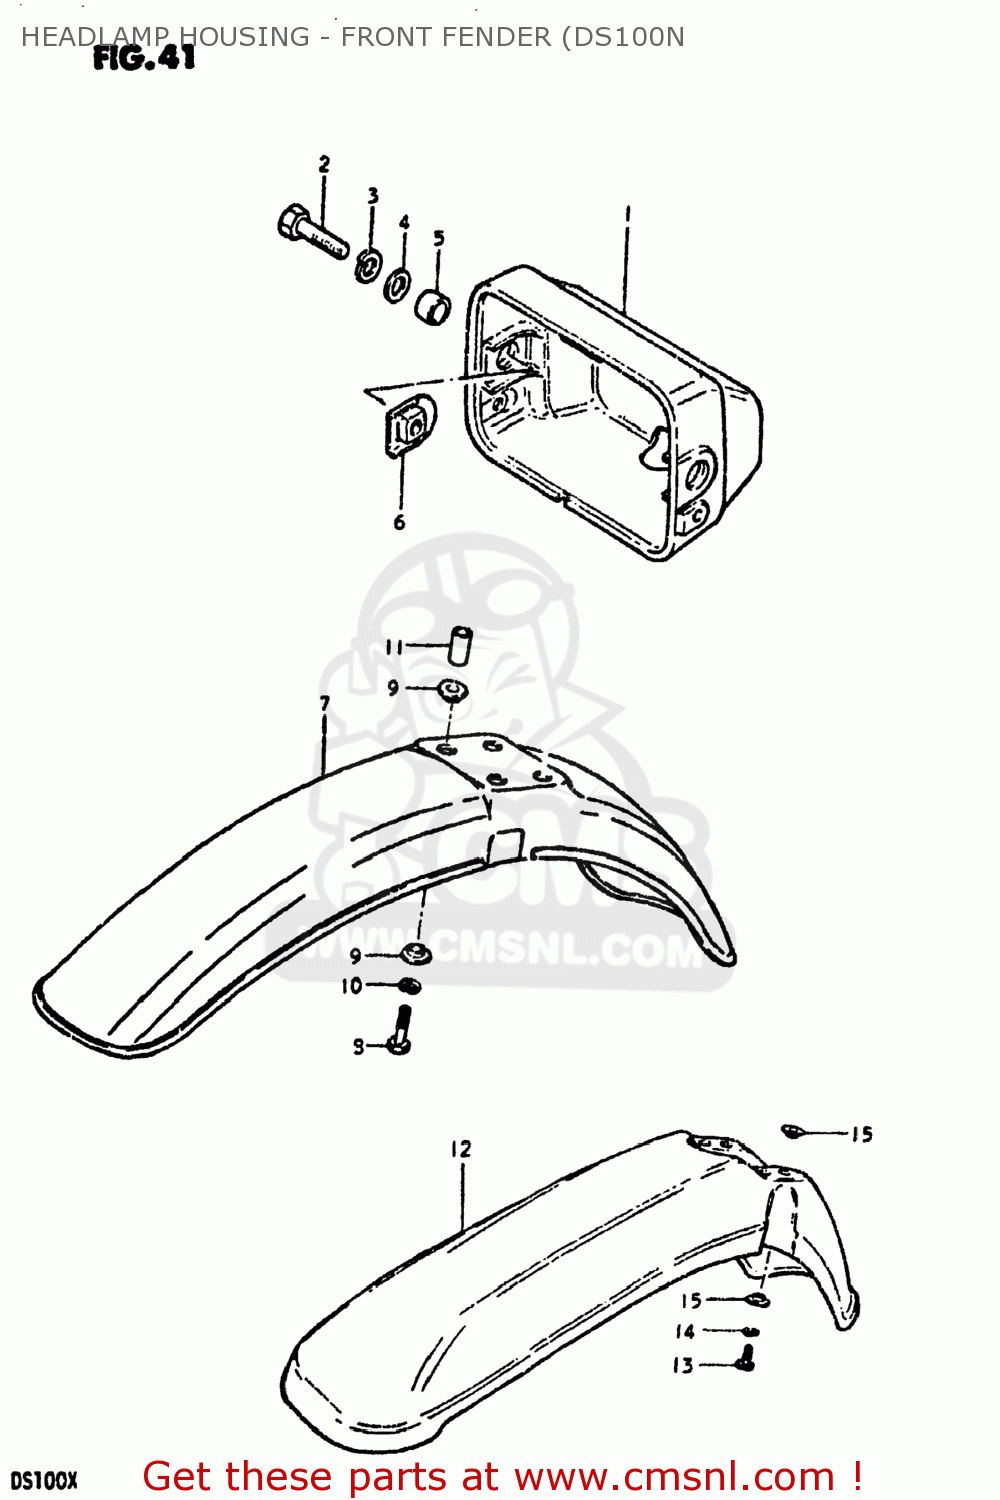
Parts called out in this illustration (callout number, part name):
1	HOUSING,HEADLAMP
2	BOLT
3	WASHER
4	LOCK WASHER
5	SPACER (8.8X12X7)
6	PLATE,HEADLAMP HOUSING
7	FENDER,FRONT
8	BOLT 6X40
9	SPACER
10	LOCK WASHER
11	SPACER (6.8X10X20)
12	FENDER,FRONT
13	BOLT, UPPER
14	LOCK WASHER
15	SPACER
